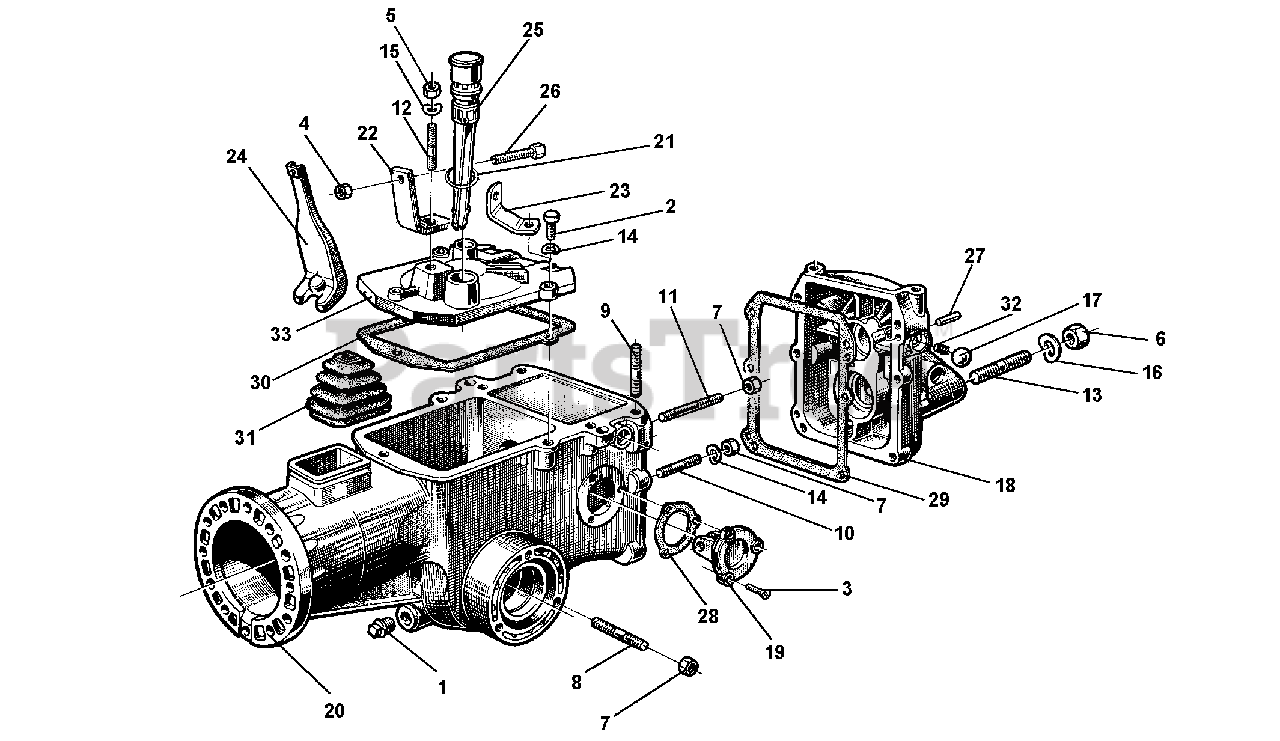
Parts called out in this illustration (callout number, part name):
1	PLUG 1/4 GAS
2	SCREW TE M8 X 30
3	SCREW TSV M6 X 16 UNI 260-5S
6	NUT M12 X 1.25 UNI 5587 6S
7	NUT, SELF LOCKING M8
8	STUD M8 X 46 X 20 X 12
9	STUD M8 X 38 X 14 X 20
10	STUD M8 X 46 X 16 X 16
11	STUD M8 X 58 X 16 X 16
12	STUD M10 X 37 X 19 X 15 8G
13	ST.56XM12X1.25X26XM12X22 8G
14	WASHER, LOCK 8.4
15	WASHER, LOCK 10.5
16	WASHER, LOCK 13
17	BALL 15/32 RIV RB-11.906
18	HOUSING COVER
19	FLANGE, REVERSE SPEED
20	CASING 5 SPEEDS GEARBOX
21	RUBBER RING
22	BRACKET CLUTCH CONTRAST
23	CONTRAST DIFFERENTIAL SHEATH
24	CLUTCH LEVER
25	CAP, WITH MEASURING ROD
26	SCREW, ADJUSTING M8
27	PARALLEL PIN D 6 X 20
29	GASKET, COVER
30	GASKET, COVER
33	COVER DIFFERENTIAL
